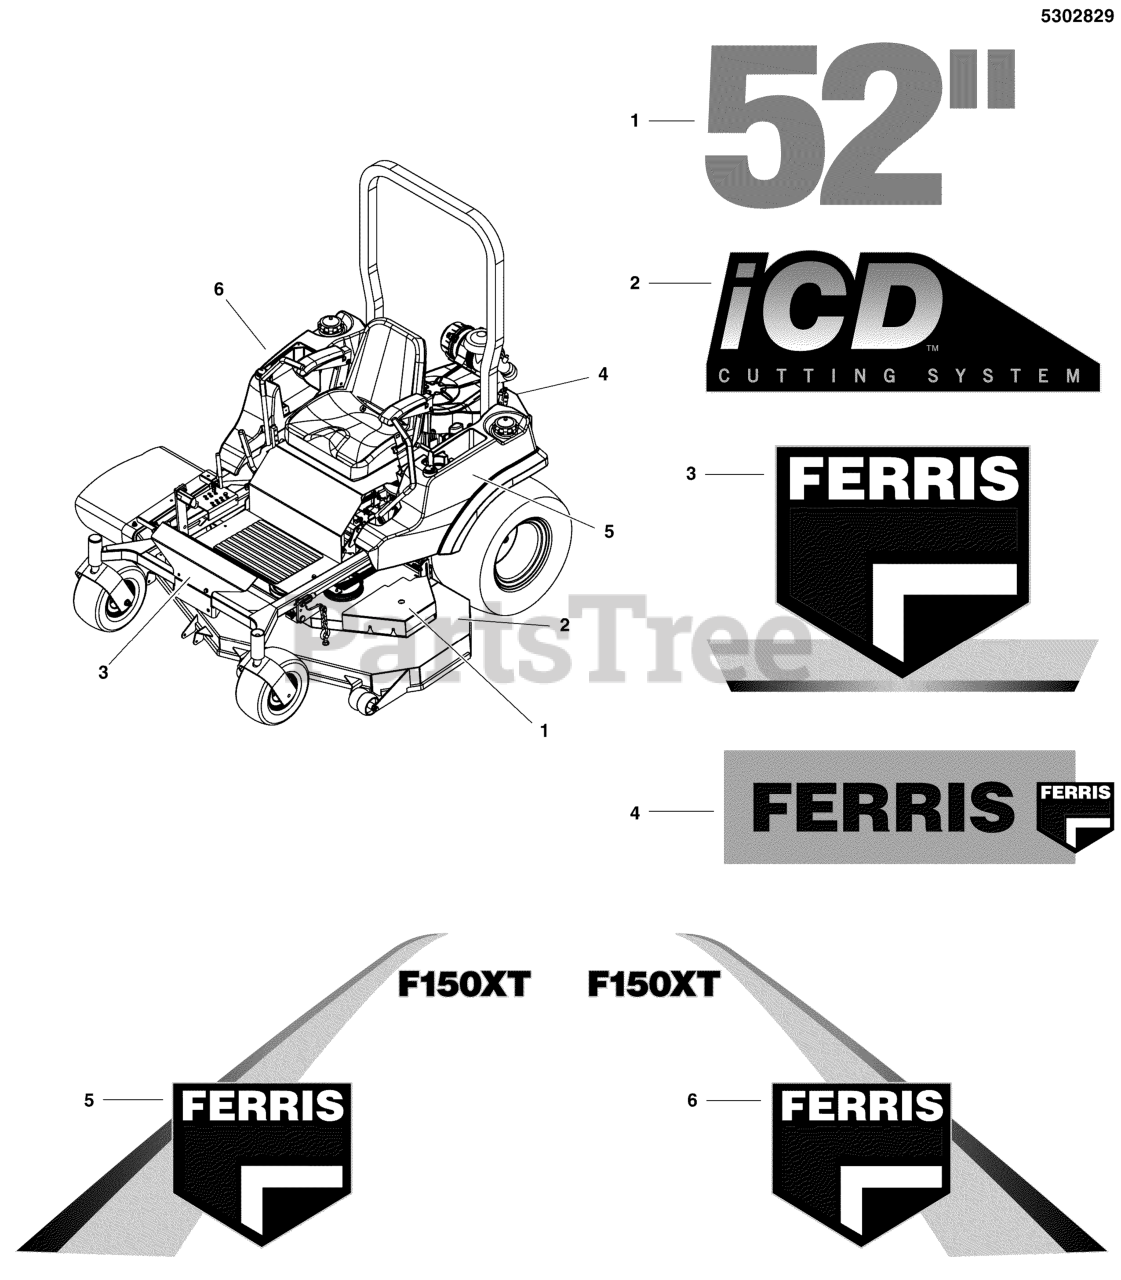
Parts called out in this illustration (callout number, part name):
1	DECAL, 52
2	DECAL, iCD CUTTING SYSTEM
3	DECAL, BADGE, FERRIS, LOGO, 3" X 6.2"
4	DECAL, FERRIS TEXT & LOGO
5	DECAL, BADGE, LH, F150XT
6	DECAL, BADGE, RH, F150XT
